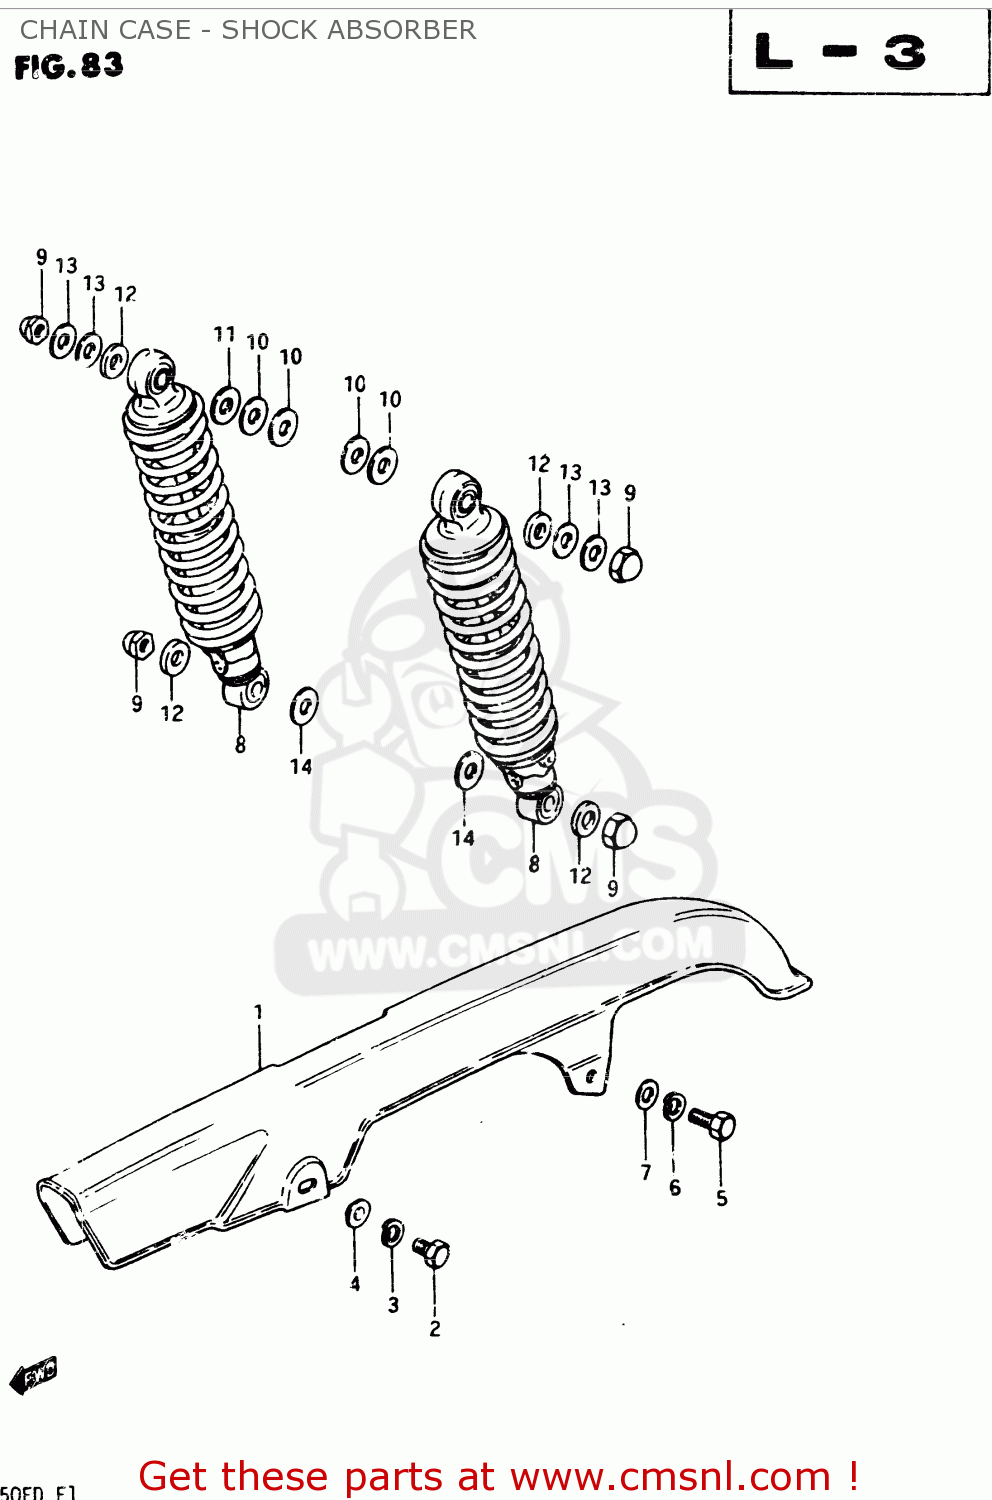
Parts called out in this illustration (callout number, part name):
1	CASE,CHAIN
2	BOLT
3	LOCK WASHER
4	WASHER,LOCK
5	BOLT
6	LOCK WASHER
7	WASHER
8	ABSORBER ASSY,RR SHOCK
9	NUT, LOWER LH
10	WASHER
11	WASHER (12.5X24X3.2)
12	WASHER
13	WASHER(10.5X24X3.2)
14	WASHER (12.5X24X1.6)
